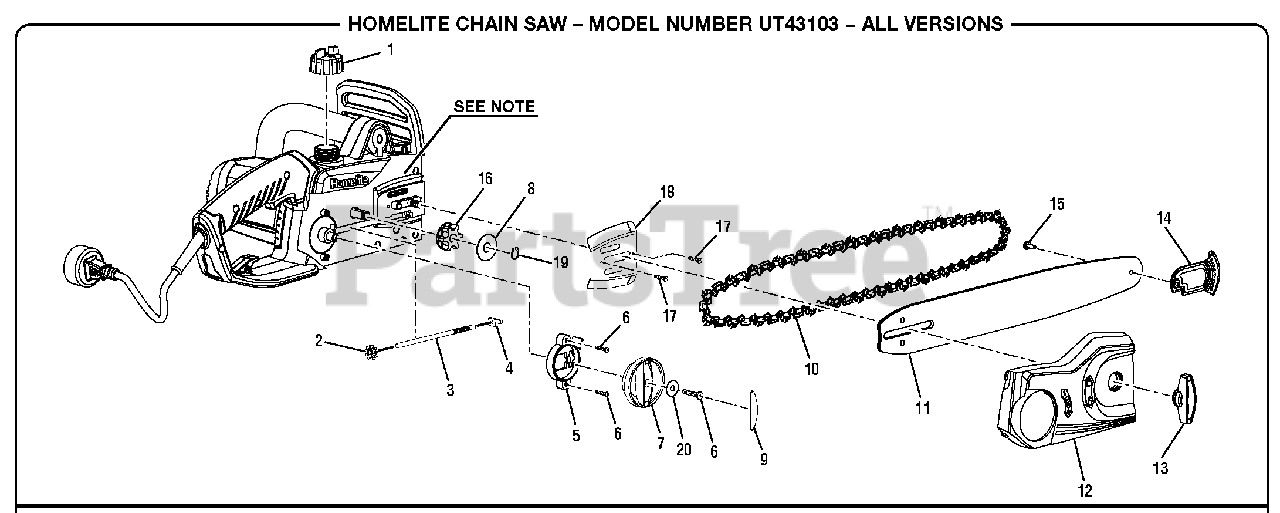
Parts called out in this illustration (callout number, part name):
1	Oil Reservoir Cap
2	Adjustment Gear
3	Adjustment Shaft
4	Adjustment Pin
5	Gear Cover
6	Screw (M4.2 x 10 mm)
7	Adjustment Knob
10	Chain (.375 x 52 link, 14 in.)
11	Guide Bar (14 in. with SAFE-T-TIP)
12	Chain Cover Assembly
13	Chain Cover Lock Knob
14	SAFE-T-TIP
15	Screw w/Washer
17	Screw (M3 x 12 mm)
18	Adjustment Pin Cover
19	Retaining Ring
20	Washer (M4)
